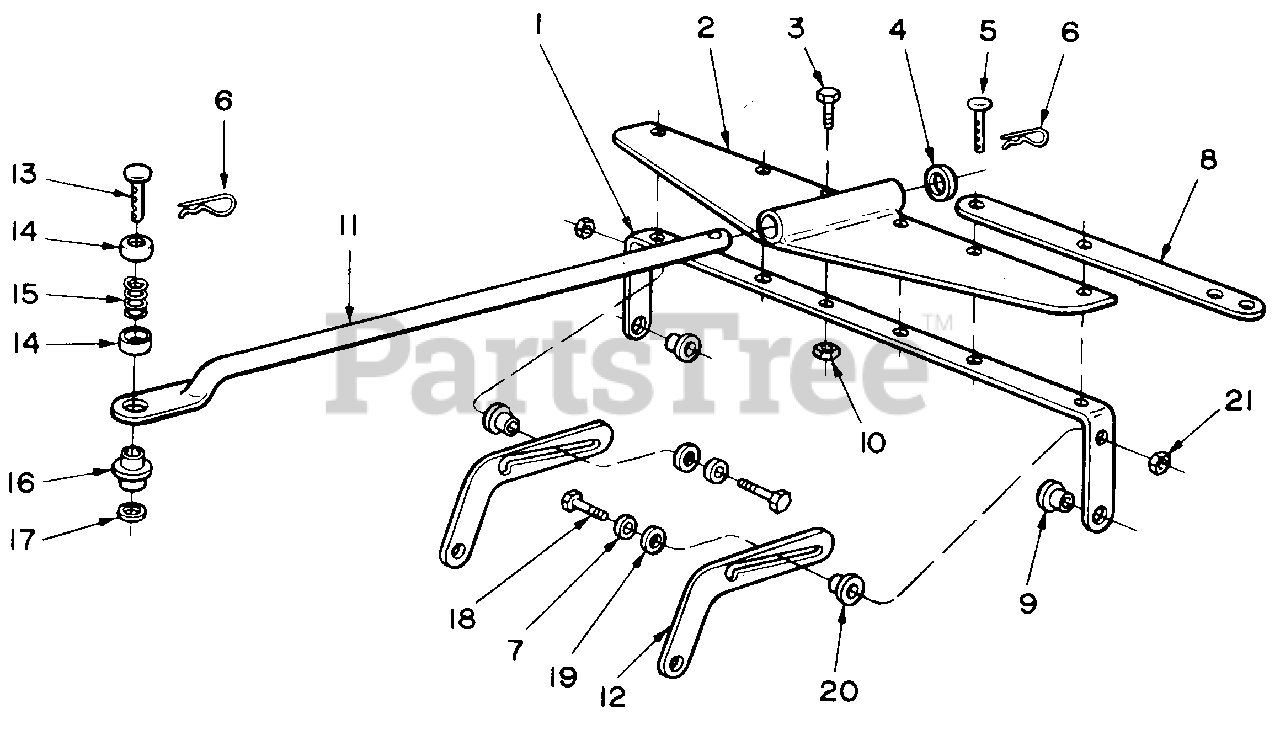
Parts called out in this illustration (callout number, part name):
1	Bridge
2	Tow Bar Plate Ass'y.
3	Bolt 5/16 x 18 x 1*
4	Washer
5	Clevis Pin
6	Cotter Pin
7	Washer-Special
8	Outrigger Bar
9	Spacer Bushing
10	Nut 5/16-18*
11	Tow Bar Ass'y.
12	Transport Brk't.
13	Clevis Pin
14	Spring Cup
15	Spring
16	Bushing
17	Washer 11/32 x 7/8*
18	Shoulder Bolt
19	Washer
20	Spacer
21	Hex L-Nut 1/4-20*
